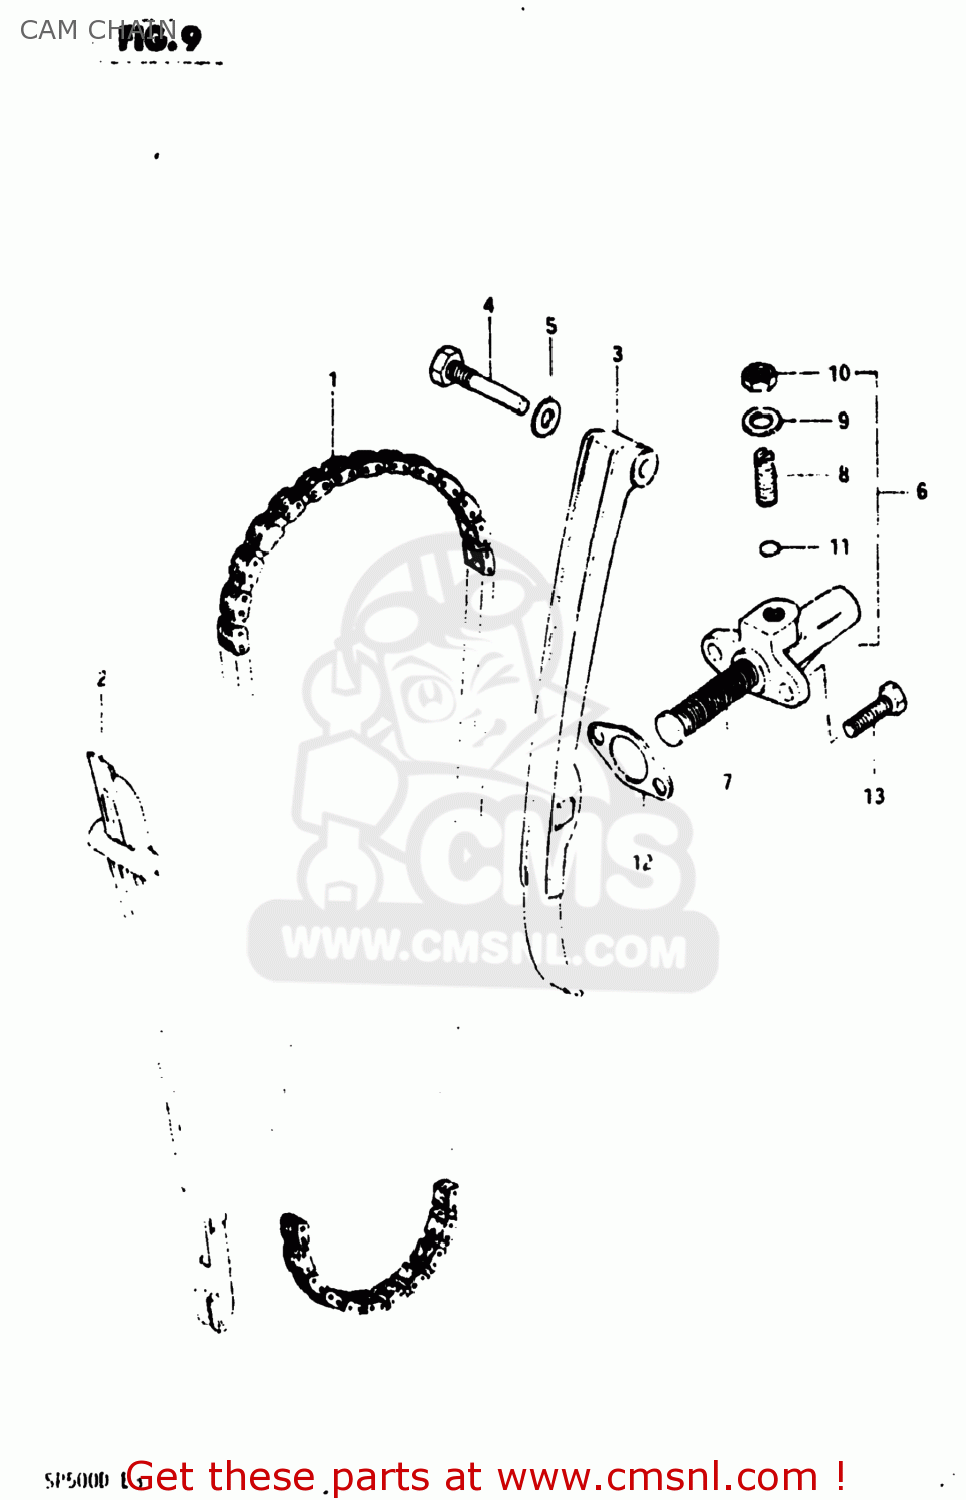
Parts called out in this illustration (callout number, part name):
1	CHAIN,CAMSHAFT DRIVE
2	GUIDE,CAM CHAIN
3	TENSIONER,CAM CHAIN
4	BOLT,CAM CHAIN TENSIONER
5	GASKET 8.2X14X1 (NAS)
6	ADJUSTER ASSEMBLY,TENSIONER
7	SPRING
8	SCREW
9	WASHER,8.5X16X
10	NUT
11	O-RING
12	GASKET,TENSIONER ADJUSTER (NAS)
13	BOLT
